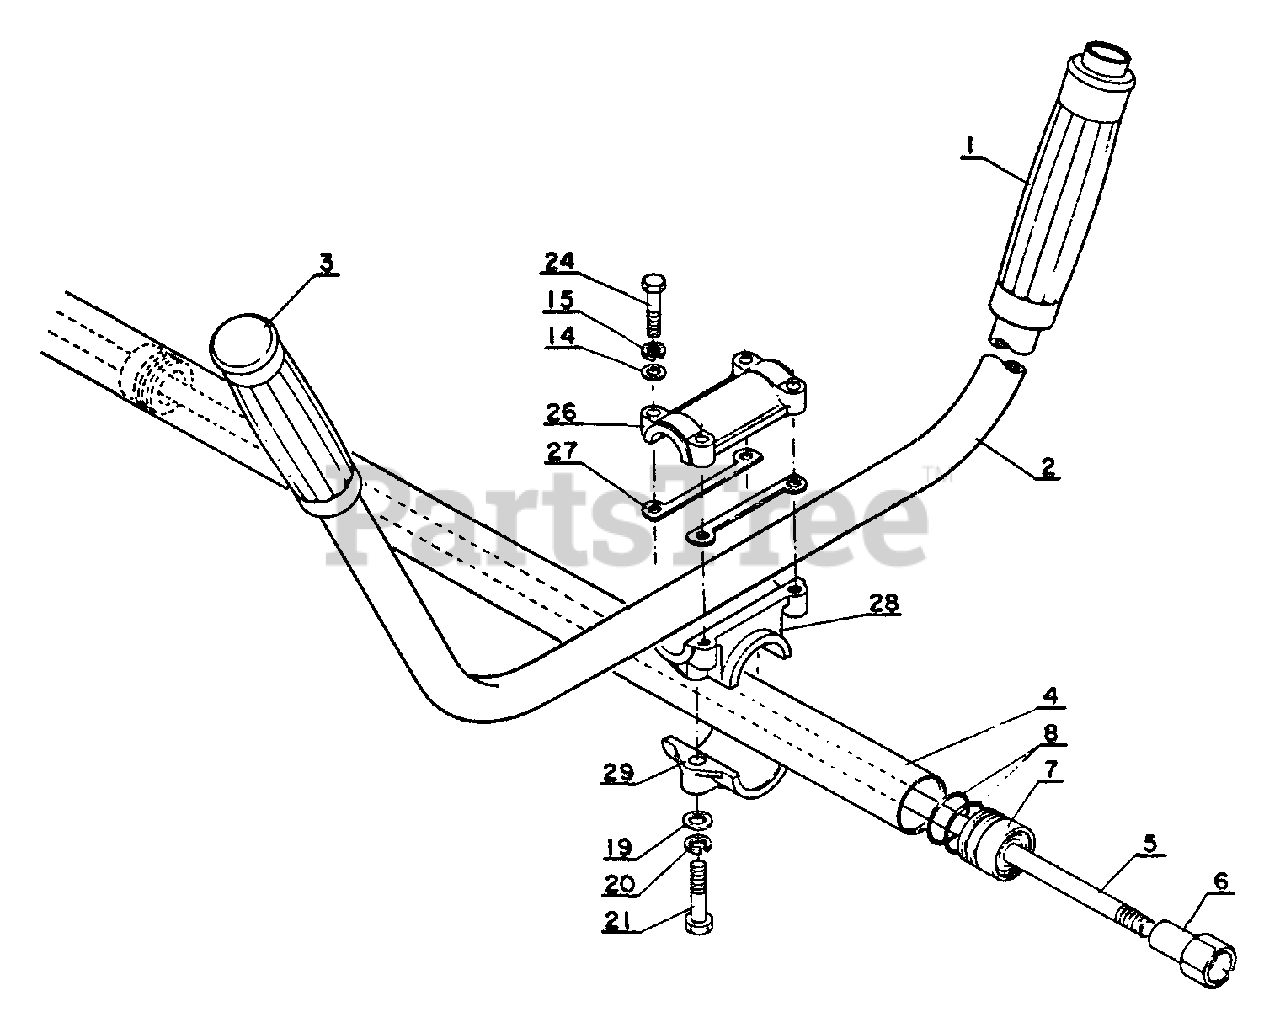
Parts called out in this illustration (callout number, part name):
1	GRIP, HANDLE
2	U-HANDLE
3	GRIP, HANDLE - LEFT
4	MAIN PIPE ASSY
5	DRIVESHAFT
6	CONNECTOR
7	STOPPER
8	O-RING - 22
19	WASHER - 6
20	LOCKWASHER - 6
21	BOLT - 6X32
24	BOLT - 5X25
26	HANDLE BRACKET KIT
28	HANDLE BRACKET KIT
29	HANDLE BRACKET KIT
